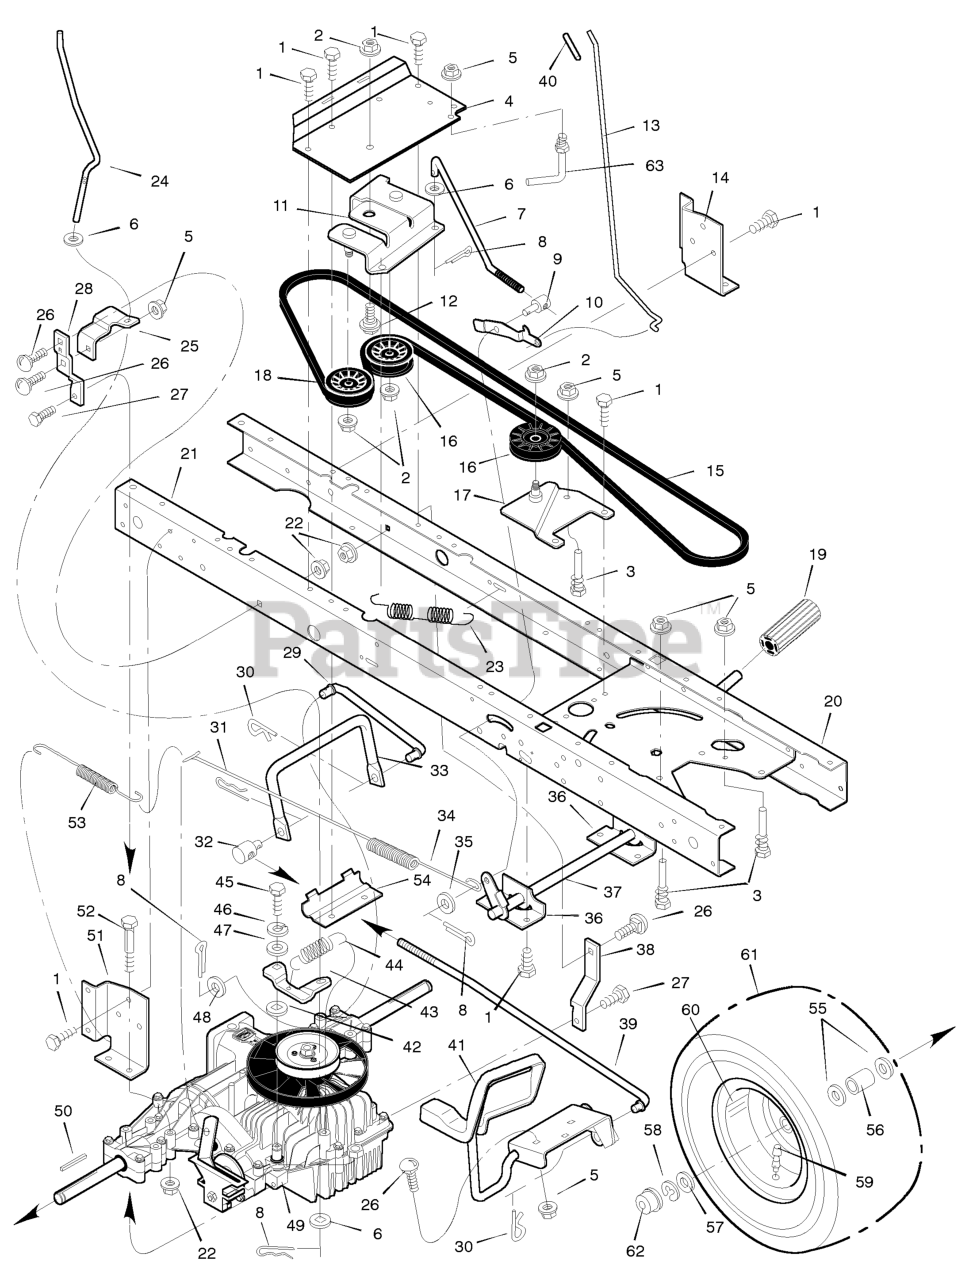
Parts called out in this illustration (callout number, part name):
2	Nut, Flange
3	Guide, Belt
4	Bracket, Idler
5	Locknut
6	Washer
7	Rod, Clutch
8	Pin, Cotter
9	Adjuster
10	Latch, Parking Brake
11	Bracket Assembly, Idler
12	Bolt, Shoulder
13	Rod, Parking Brake
14	Bracket, Transaxle
16	Pulley, Idler
17	Arm Assembly, Idler
18	Pulley, Idler
19	Pedal
20	Frame, Left
21	Frame, Right
22	Nut, Flange
23	Spring, Extension
24	Rod, Disconnect
25	Bracket, Disconnect
26	Bolt, Carriage
28	Strap, Right Torque
29	Rod, Link
30	Pin, Hair
31	Pin, Hair
32	NUT, Adjusting, 1/2-13
33	Rod, Yoke
34	Spring, Extension
35	Washer
36	Bracket, Pivot
37	Lever, Clutch/Brake
38	BRACKET, Torque Strap, LH
39	Rod, Link
41	Pedal, Speed Control
43	Arm, Disconnect
44	Spring
46	Lockwasher
48	Washer
49	Transaxle **
50	Key, Square
51	Bracket, Right Transaxle
52	Bolt
53	Spring, Extension
54	Clamp, Transaxle
58	E- Ring
59	Valve Stem
60	Wheel & Tire Assembly
61	Tire *
62	Cap, Hub
63	Guide, Belt
